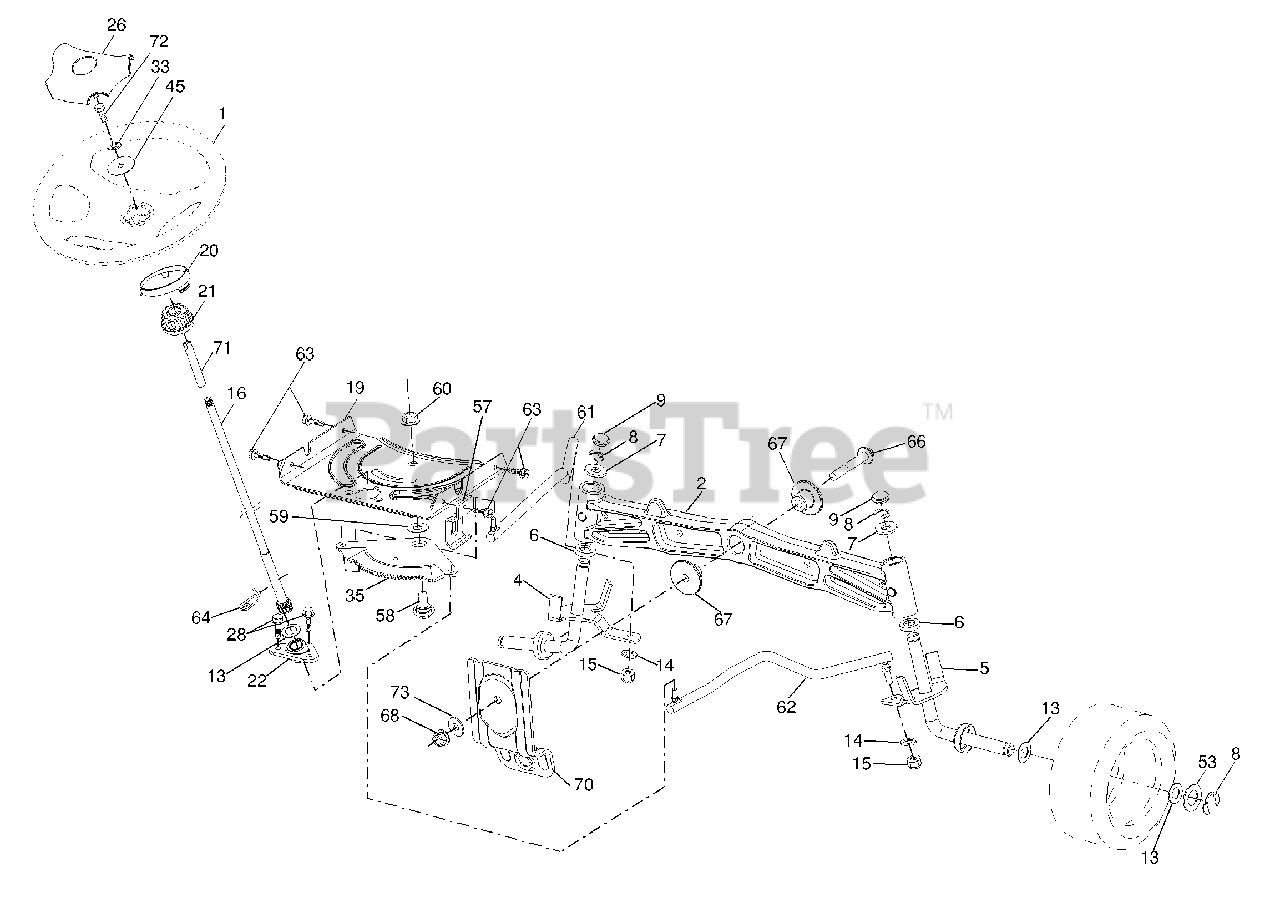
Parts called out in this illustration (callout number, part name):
1	Wheel, Steering
2	Axle Asm., Front
4	Spindle Asm., LH
5	Spindle Asm., RH
6	Bearing, Race Thrust Harden
7	Washer 25/32 x 1-5/8 x 16 Ga.
8	Ring, Clip #T5304-75
9	Cap, Spindle
13	Washer 25/32 x 1-1/4 x 16 Ga.
14	Washer, Lock Hvy Hlcl Spr 3/8
15	Nut, Crown Lock 3/8-24 unf
16	Shaft Steering
19	Plate Steering
20	Boot, Steering
21	Adapter, Wheel Steering
22	Bushing, Strg. Blk
26	Insert, Wheel Steering
28	Screw 3/8-16 x 3/4
33	Washer Lock 5/16
35	Gear, Sector Plate
45	Washer 11/32 x 3/8 x 12 Ga.
53	Washer Hardened .793 x 1.637 x .060
57	Bracket Upstop
58	Bolt Shoulder Sector Pivot CFM
59	Washer Thrust Sector Steering
60	Nut Flange Lock 5/8-11
61	Draglink, LH
62	Draglink, RH
63	Screw 5/16-18 x 3/4
64	Retainer Clip Spring Steering
66	Bolt Hex Fghd 7/16-14 x 3 Serr
67	Bushing PM Front Axle
68	Nut Lock Flange 7/16-14 Gr. 5
70	Bracket Deck Susp. Front
71	Shaft Extension Steering
72	Bolt 5/16-18 unc x 4.5. Gr. 5
73	Washer 1.5 x .505 x .118
